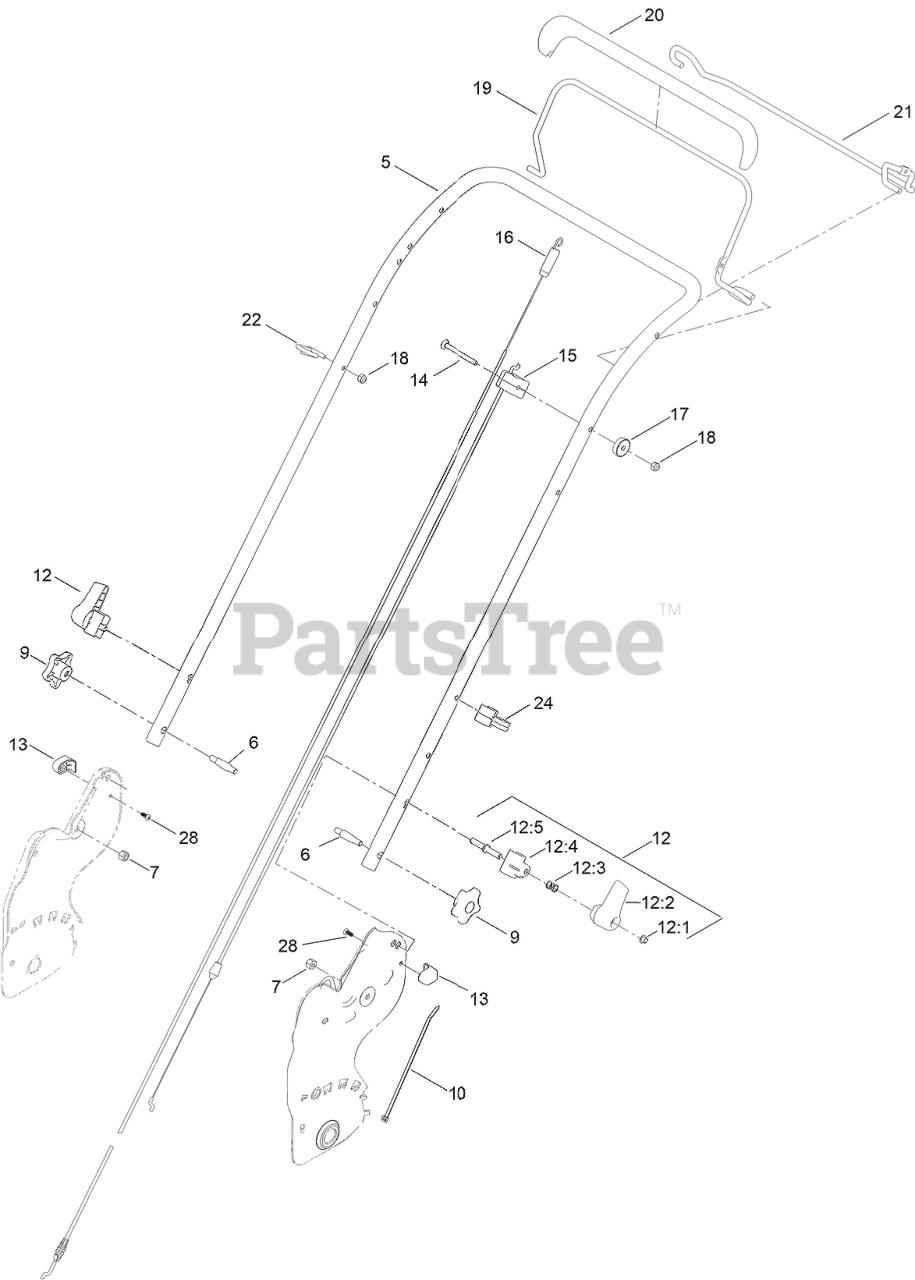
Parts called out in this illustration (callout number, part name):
5	HANDLE-CURVED
6	BOLT-SHOULDER, HANDLE
7	NUT-LOCK, NI
9	KNOB-HANDLE
10	TIE-CABLE
12	QUICK RELEASE ASM
12:1	NUT-PUSH
12:2	LEVER-RELEASE
12:3	ANCHOR-SPRING
12:4	SPRING-COMPRESSION
12:5	ROD-RELEASE
13	PAD-SMART STOW
14	SCREW-CARR
15	CABLE-BRAKE, FWD
16	CABLE-TRACTION, FWD
17	WASHER-CURVED
18	NUT-LOCK, NI
19	BAIL-BRAKE
20	COVER-BAIL
21	BAIL-TRACTION
22	GUIDE-ROPE
24	GUIDE-CABLE
28	SCREW-PLASTITE
